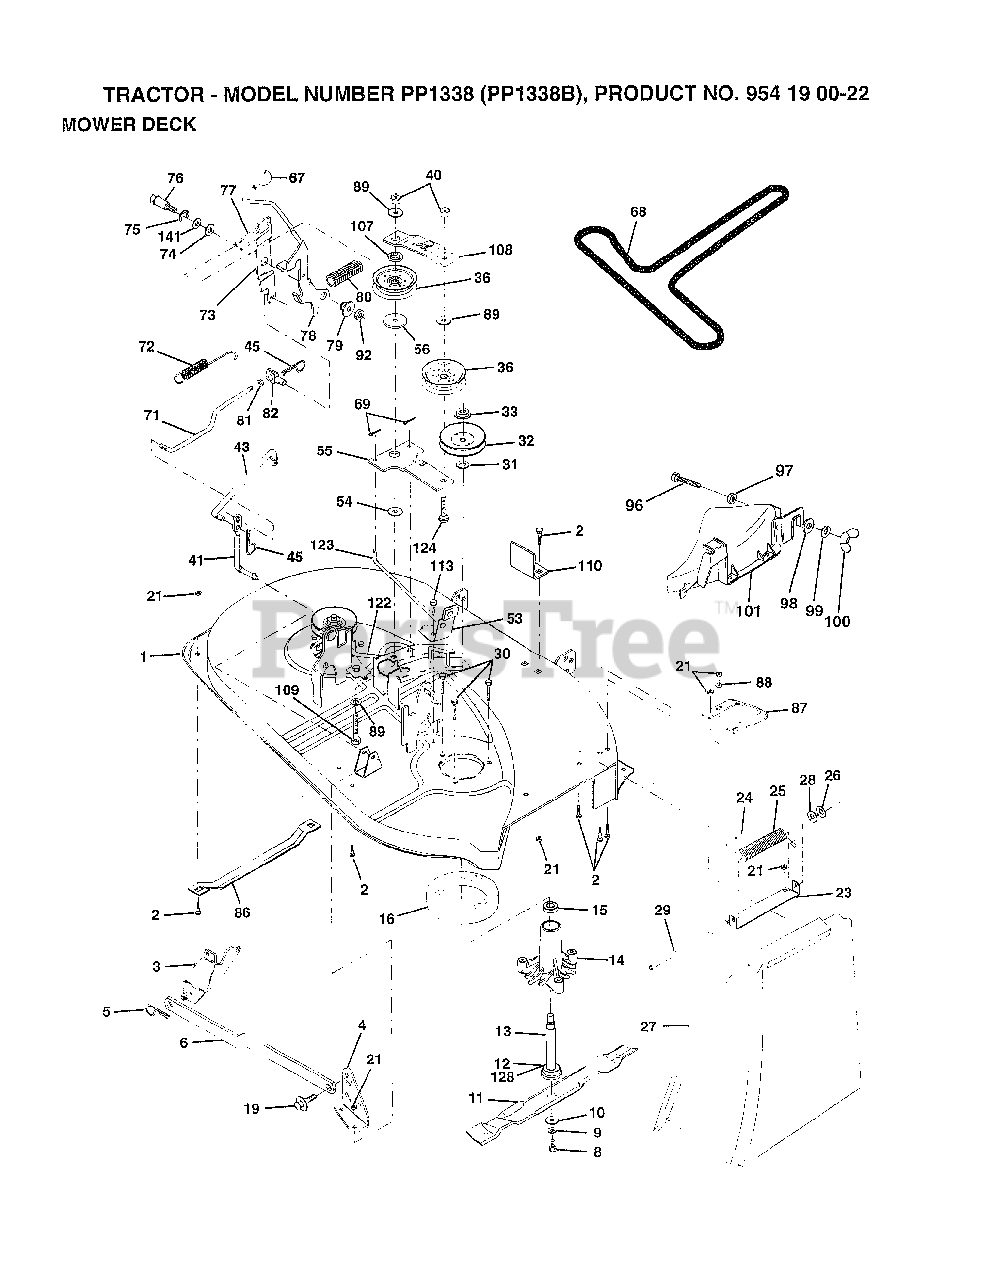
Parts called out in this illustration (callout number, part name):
3	BRKT ASM SWAY BAR
4	BRKT DECK SW BAR
8	BLADE BOLT
10	WASHER.HARD.BLADE
11	"BLADE.38""V.MULCH"
12	BEARING.BALL
14	HSG ASM MANDREL
15	BEARING
16	STRIPPER RND MWR
19	BOLT SHD 5/16-18
23	BRKT DEFLECTOR
25	SPRING TORSION
27	DEFLECTOR-SHLD T
28	WASHER
29	ROD-HINGE T
30	"SCREW-THD ROLL,WA"
31	WASHER
32	PULLEY.MANDREL.38
36	FLAT IDLER PULLEY
41	PIVOT ROD
43	CLUTCH ROD SECOND
53	BRAKE ASM
54	HARDENED WASHER
55	IDLER ARM ASSY
56	SPACER RETAINER
67	KNOB.RD.7/16-14
68	BELT.V.T-PATH
71	ROD CLUTCH 38/42
72	RETURN SPRING
73	CLUTCH ARM SECOND
74	WASHER
75	RING
76	SHOULDER BOLT
77	SPRING KEEPER
78	ARM.ASM.CLUTCH.
79	BUSHING
80	SPRING.CLUTCH.MWR
81	NUT
82	TRUNION ADJ
86	RUNNER-LH M
87	RUNNER RH
88	WASHER M
89	WASHER GT
92	NUT
96	HEX BOLT
97	LOCKNUT
99	LOCKWASHER
100	WINGNUT
101	COVER.MULCHER
107	RETAINER SPACER
108	IDLER ARM STIFF
109	BOLT
110	UPSTOP DECK FT 38
113	SCREW
122	BRAKE ROD LH
123	BRAKE ROD RH
124	BOLT
128	WASHER.FELT.
141	WASHER .T
